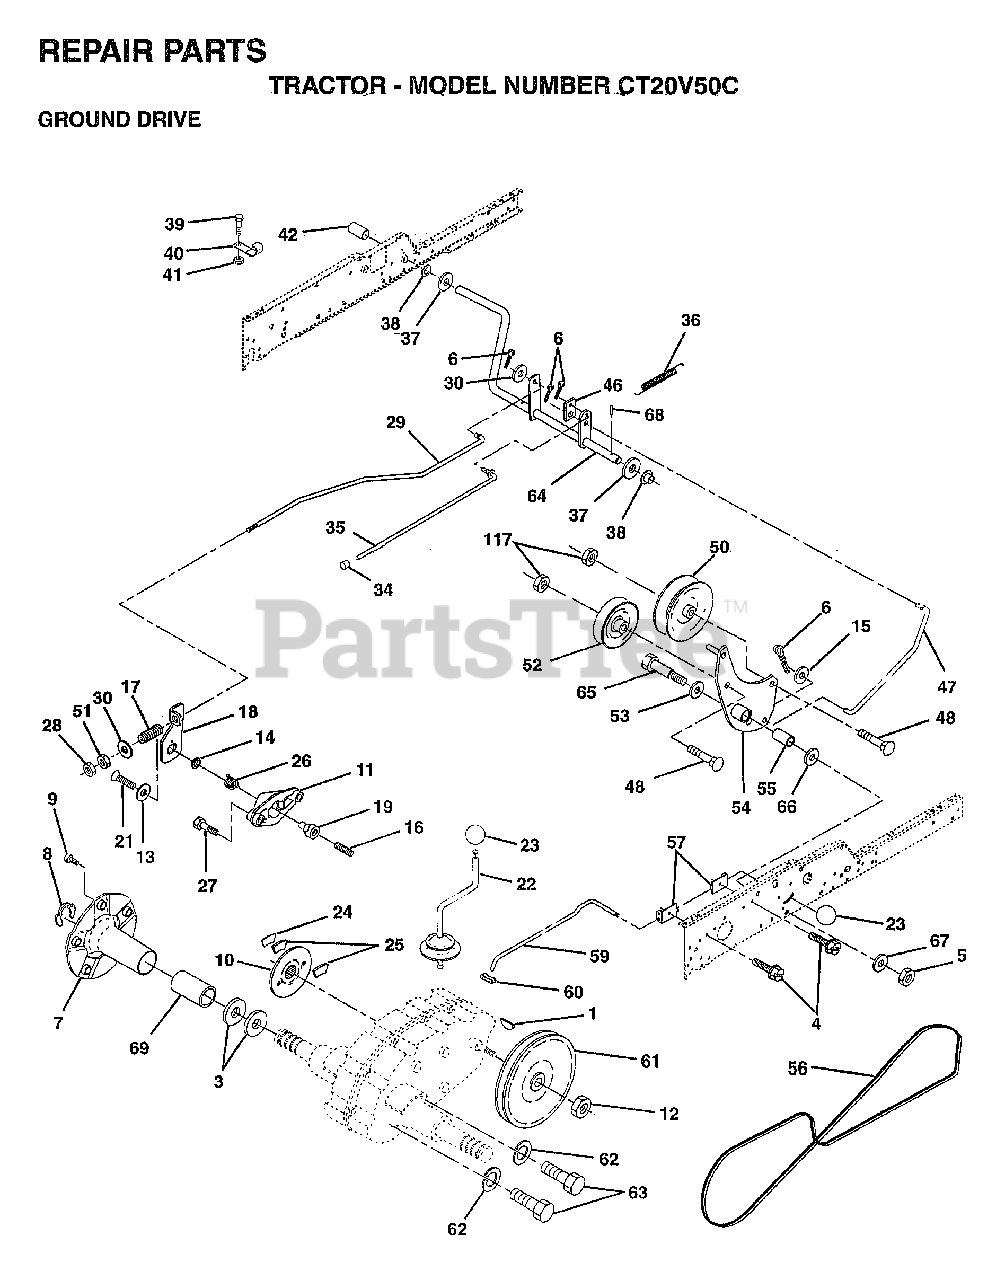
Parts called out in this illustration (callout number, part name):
3	WASHER T
4	SCREW LT
6	COTTER PIN
8	KLIP RING
9	BOLT.HUB.WHL.REAR
10	BRAKE.DISC.
11	YOKE BRAKE DISC
12	NUT STD
13	WASHER SPECIAL
14	BUSHING LEVER BKT
15	WASHER
16	SCREW SET 1/4-20
17	"SPRING,ROD BRAKE"
18	LEVER BRAKE GT
19	CAM BRAKE DISC GT
21	SCREW FLT 1/4X28
22	GEAR SHFT LVR T
23	KNOB T(3/8 HOLE)
24	SUPPORT PUCK BRKE
25	PUCK BRAKE TOP
26	SPRING RET BRAKE
27	SCREW HX WASH
28	NUT
29	ROD BRAKE ZINC GT
30	WASHER HYT
34	PLUNGER CAP T
35	ROD BRAKE PART GT
36	SPRING.GRND.DRIVE
37	WASHER
38	BUSHING.NYLINER
39	SCREW
40	ACT-SWITCH T
42	PEDAL COVER T
46	RETAINER.SPRING
47	ROD.CLUTCH
48	BOLT.3/8-16X1.50
50	FLAT IDLER PULLEY
52	PULLEY.IDLER.V.GR
53	WASHER T
54	ARM ASM CLUTCH
55	"LY, BEARING"
56	BELTV.GR.DR.83.
57	BRACKET.ROD.SHIFT
59	ROD SHIFT HI LO
60	CONNECTING LINK
62	LOCKWASHER
63	BOLT
64	SHAFT-BRAKE/CLUTC
65	AXLE BOLT
66	WASHER.HARD.BLADE
67	WASHER
68	ROLL PIN STD
69	"COVER, HUB"
